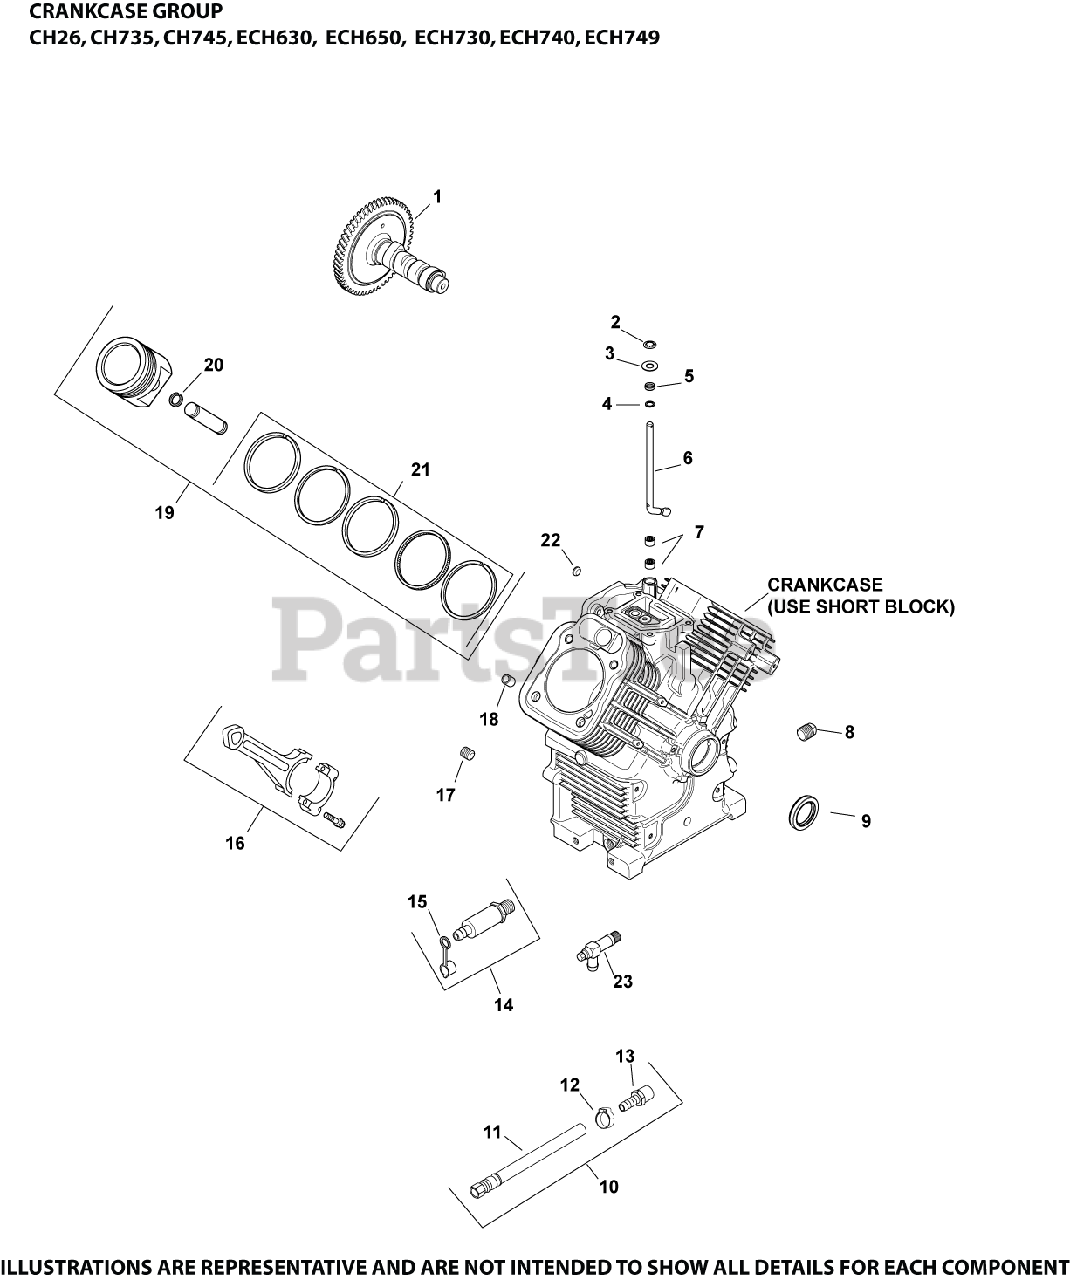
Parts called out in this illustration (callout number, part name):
1	KIT, CAMSHAFT
2	RETAINER, RING
3	WASHER, FLAT 9 MM
4	WASHER, FLAT 11/32"
5	SEAL, GOVERNOR CROSS SHAFT
6	SHAFT, GOVERNOR CROSS
8	PLUG, HD PIPE 3/8"
9	SEAL, OIL (HELIX LIP)
16	ROD ASSY,CONNECTING USE 24 067 34-S
18	PIN, LOCATING
19	PISTON W/RINGS (STYLE A)(STD) - USE 24 874 58-S
19	PISTON W/RINGS (STYLE A)(.08) - DISCONTINUED
20	RETAINER, PISTON PIN
21	RING SET (STYLE A)(STD) 1.5MM TOP RING THICKNESS USE PISTON ASSY PER SPEC - Discontinued
22	PLUG, CUP
